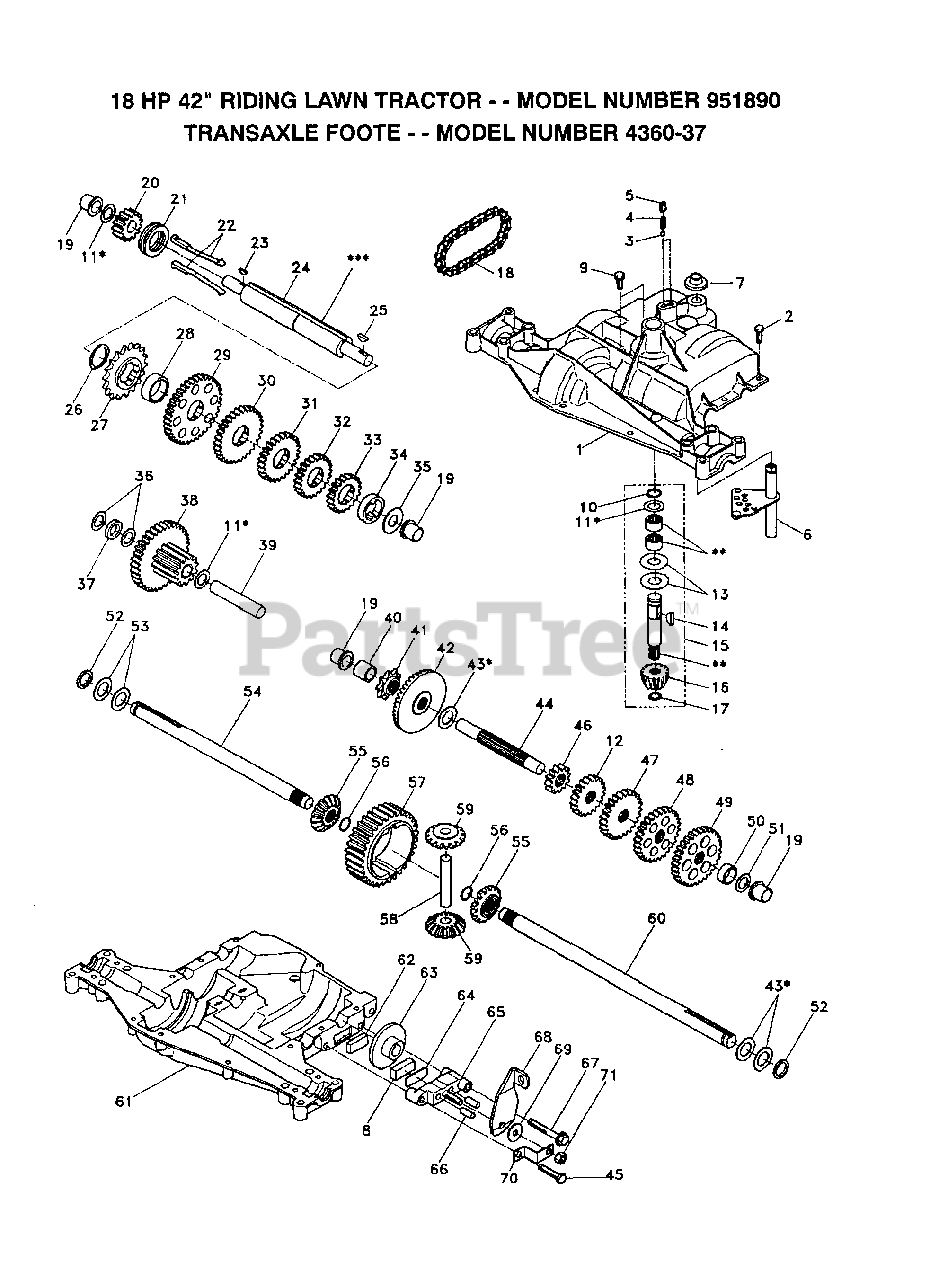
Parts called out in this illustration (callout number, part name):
1	HOUSING UPPER
3	BALL, DETENT
4	SPRING, DETENT
5	SCREW, SET
6	KIT SHIFTER ASSY
7	BOOT, SHIFTER
8	PUCK, FRICTION
9	SCREW TAPPING WITH SEALER
10	RING RETAINING
11	ASSY, KIT, SHIM .625 SHAFT
12	GEAR SPUR, 15 TEETH
13	WASHER, PLAIN .632 X 1.38 X .046
14	KEY WOODRUFF #9
15	ASSY KIT INPUT SHAFT
16	PINION BEVEL 14 TEETH
17	RING, RETAINING
18	CHAIN, 24 PITCHES
19	BEARING, FLANGE
20	GEAR SPUR, 14 TEETH
21	COLLAR CLUTCH
22	KEY CLUTCH
23	KEY WOODRUFF #3
24	SHAFT INTERMEDIATE
25	KEY, WOODRUFF, #61
26	RING, RETAINING
27	SPROCKET, 18 TEETH
29	GEAR, SPUR, 37 TEETH
30	GEAR, SPUR, 35 TEETH
31	GEAR, SPUR, 30 TEETH
32	GEAR, SPUR, 25 TEETH
33	GEAR, SPUR, 22 TEETH
34	GEAR, SPUR, 19 TEETH
35	WASHER, PLAIN .640 X 1.37 X .061
36	WASHER, PLAIN .632 X 1.00 X .026
37	SPACER .630 X 1.00 X .169
38	ASSY GEAR COMB 12&35 TEETH
39	SHAFT, IDLER
40	SPACER .635 X .875 X .755
41	SPROCKET, 9 TEETH
42	GEAR, BEVEL, 42 TEETH
43	ASSY, KIT, SHIM .750 SHAFT
44	SHAFT, DRIVE
45	SCREW TAPPING
46	GEAR, SPUR, 12 TEETH
47	GEAR, SPUR, 20 TEETH
48	GEAR, SPUR, 25 TEETH
49	GEAR, SPUR, 28 TEETH
50	GEAR, SPUR, 31 TEETH
51	WASHER, PLAIN .632 X 1.00 X .060
52	WASHER, NEOPRENE
53	WASHER, PLAIN .758 X 1.25 X .031
54	AXLE LEFT HAND
55	GEAR MITER 15 TEETH
56	RING, RETAINING
57	GEAR, SPUR, 32 TEETH
58	SHAFT, CROSS
59	GEAR, MITER, 15 TEETH
60	AXLE, R.H.
61	HOUSING LOWER
62	PUCK, FRICTION
63	DISC, BRAKE
65	JAW, BRAKE
66	PIN, DOWEL
67	SCREW, SELF-TAPPING
68	LEVER, ACTUATING
69	WASHER, PLAIN .321 X 1.00 X .055
70	BRACKET, ANTI-ROTATION
71	LOCKNUT 5/16-24
